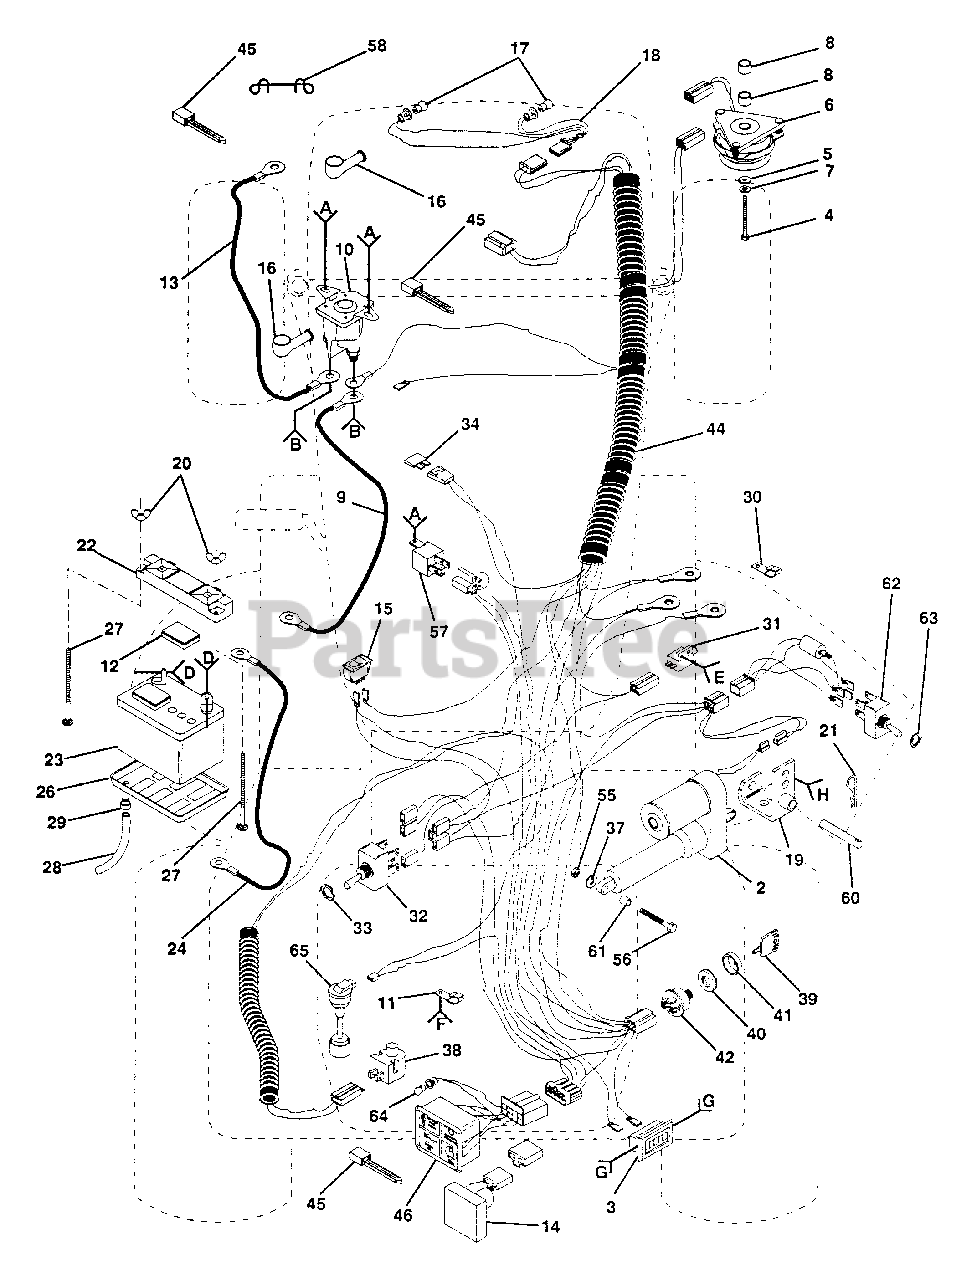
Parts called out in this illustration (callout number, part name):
2	Actuator, Electric
3	Meter, Hour
4	Bolt, Hex 7/16-20 x 1-1/2 Grade 8
6	Clutch, Electric
7	Washer, Lock 7/16
8	Spacer, Clutch
9	Cable, Battery
10	Solenoid
11	Clip, Insulated
12	Battery Caps
13	Cable, Starter
14	Sensor, Low Voltage
15	Switch, Light
16	Cover, Terminal
17	Bulb, Light
18	Harness, Light Socket
19	Bracket Assembly, Actuator
20	Nut, Wing 1/4-20
21	Spring, Retainer
22	Guard, Terminal
23	Battery
24	Cable Ground
26	Tray, Battery
27	Bolt, Carriage 1/4-20 x 7-1/2
28	Tube, Plastic
29	Clamp, Hose
31	Switch, Interlock
32	Switch, P.T.O.
33	Nut, Hex
34	Fuse
37	Washer, Lock 3/8
38	Switch, Seat
40	Nut, Ignition
41	Bezel, Ignition
42	Switch, Ignition
44	Harness, Ignition
45	Cable Tie
46	Light Package
55	Nut, Fin Hex 3/8-16
56	Bolt, Fin Hex 3/8-16 x 2-1/4
57	Assembly, Relay
60	Pin, Actuator
62	Switch Assembly, Lift
63	Washer, Lock
64	Bulb, Dashboard, Light
65	Sensor, Low Fuel
